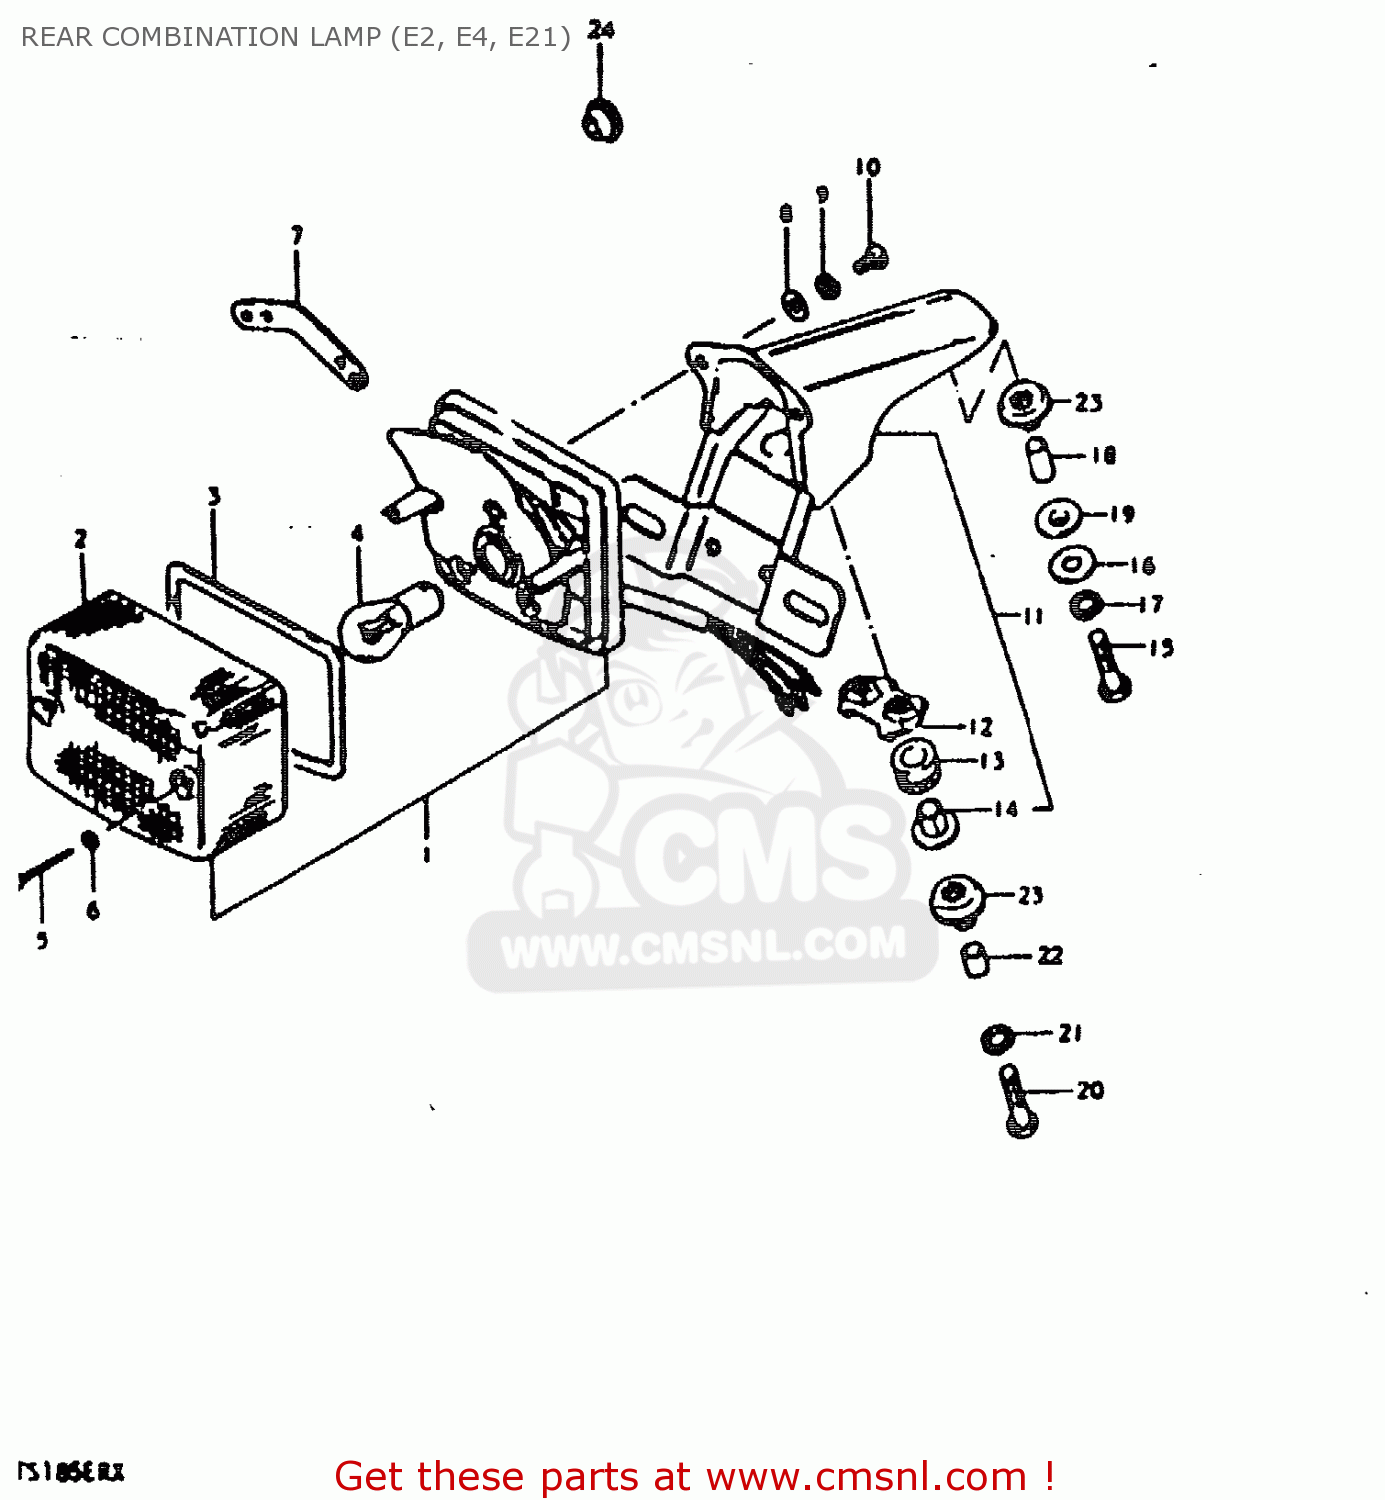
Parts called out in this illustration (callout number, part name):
1	LAMP UNIT, TAIL
2	LENS
3	GASKET (NAS)
4	BULB (6V,21/5W)
5	BOLT
6	GASKET (NAS)
7	PLATE,REAR COMBINATION LAMP
8	WASHER
9	LOCK WASHER
10	SCREW
11	BRACKET ASSY
12	PLATE
13	CUSHION
14	SPACER
15	BOLT
16	WASHER (6.5X20X1.2)
17	LOCK WASHER
18	SPACER
19	CUSHION
20	BOLT 6X40
21	LOCK WASHER
22	SPACER (6.8X10X11.5)
23	CUSHION
24	GROMMET
